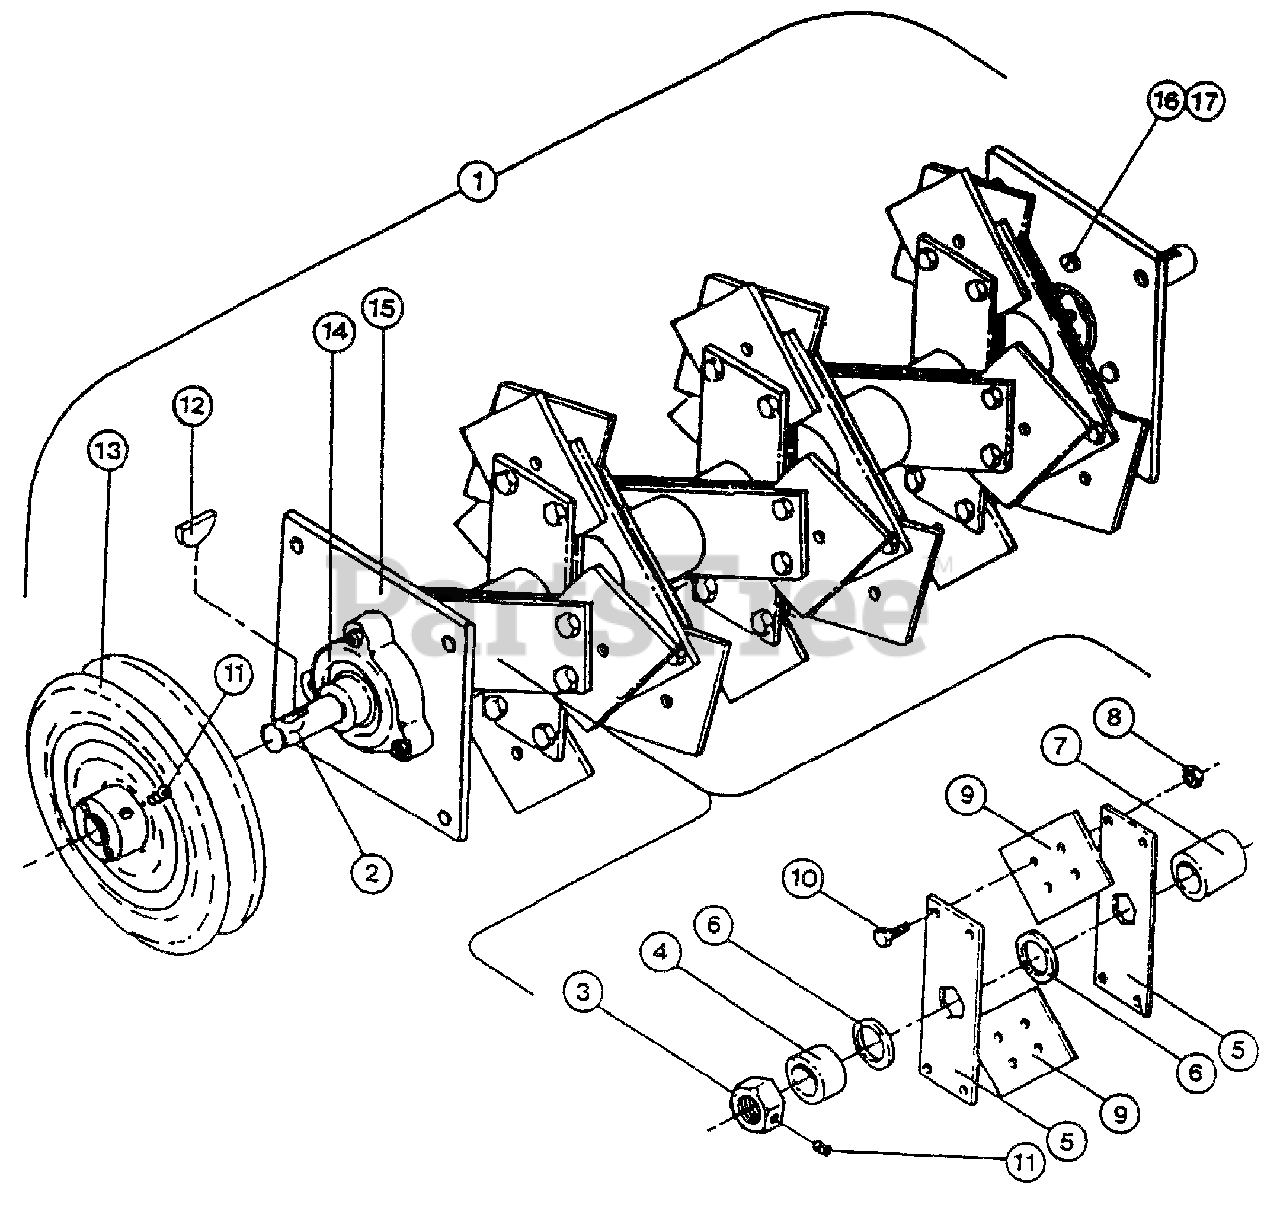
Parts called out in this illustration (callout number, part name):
1	"Quick-Change" Slicer Shaft Assembly
2	Slicer Shaft, Bare
3	Jam Nut w/Set Screw
4	Sleeve Spacer (Short)
5	Blade Holder Plate
6	Blade Washer
7	Sleeve Spacer (Long)
8	1/4-20 Nyloc Nut
9	Slicer Blade
10	1/4-20 x 5/8 Hex Cap Screw
11	5/16-18 x 3/8 Set Screw
12	#9 Woodruff Key
13	Main Shaft Pulley
14	Flanged Bearing
16	5/16-18 x 1-1/4 Tap Bolt
17	5/16-18 Nyloc Nut
